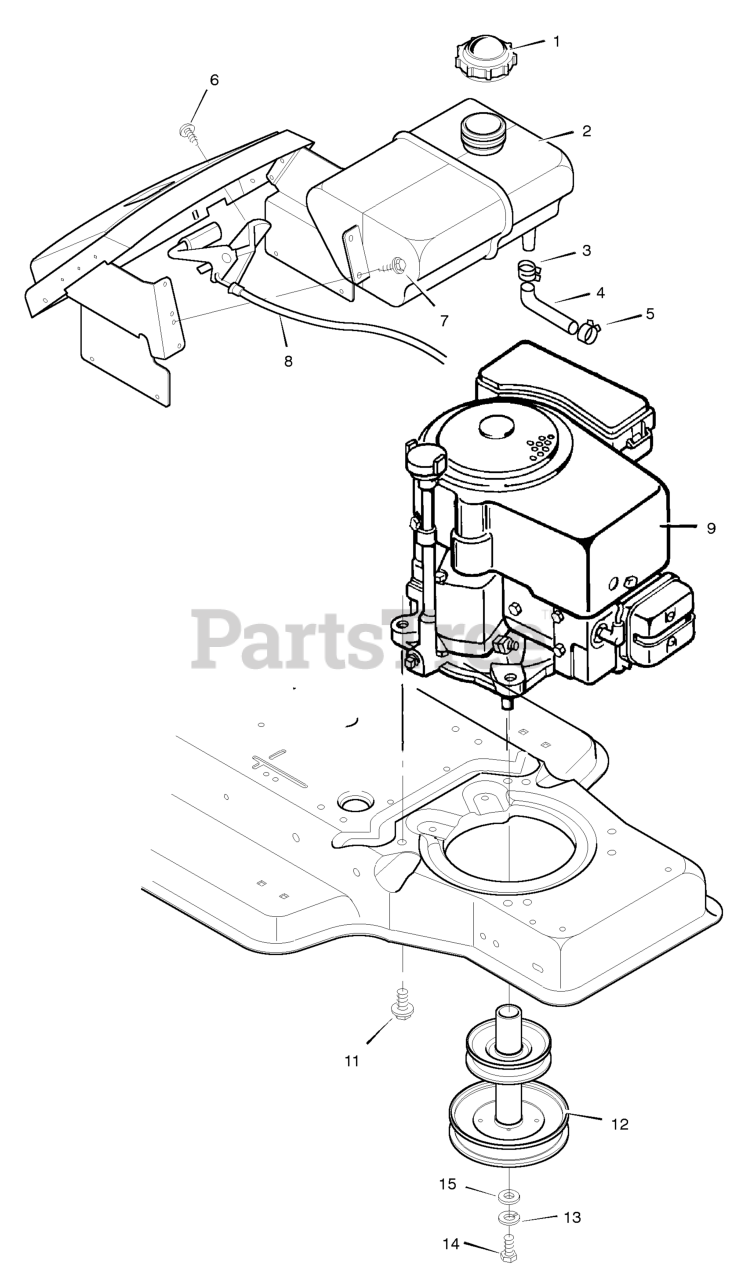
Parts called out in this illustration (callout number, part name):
1	Fuel Cap
2	Fuel Tank
3	Hose Clamp
4	Fuel Line
5	Hose Clamp
8	Throttle Control
9	Engine *
11	Bolt, Engine Mount
12	Stack Pulley Assembly
13	Lockwasher
14	Bolt, Hex
